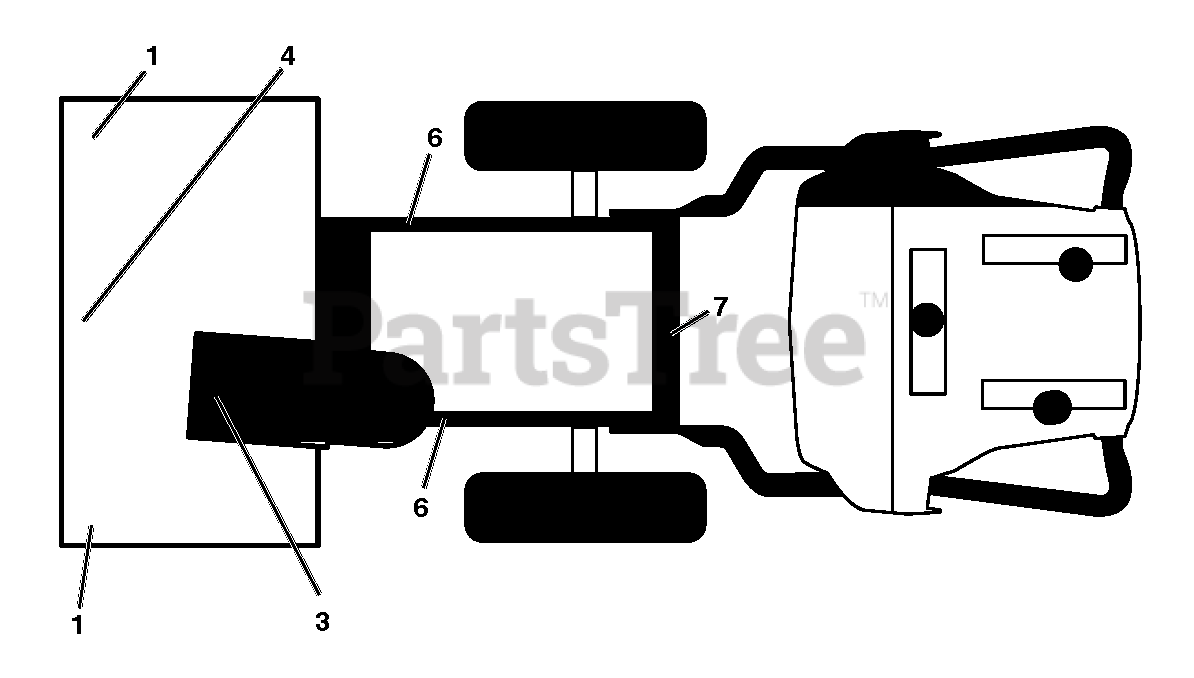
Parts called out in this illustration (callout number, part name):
1	DECAL.AUGER.SAFETY.
3	DECAL.CHUTE.SAFETY.
4	DECAL.AUGER."
6	DECAL.BELT.GUARD.
7	DECAL.NOISE.LEVEL.105DB/CE.EAC
